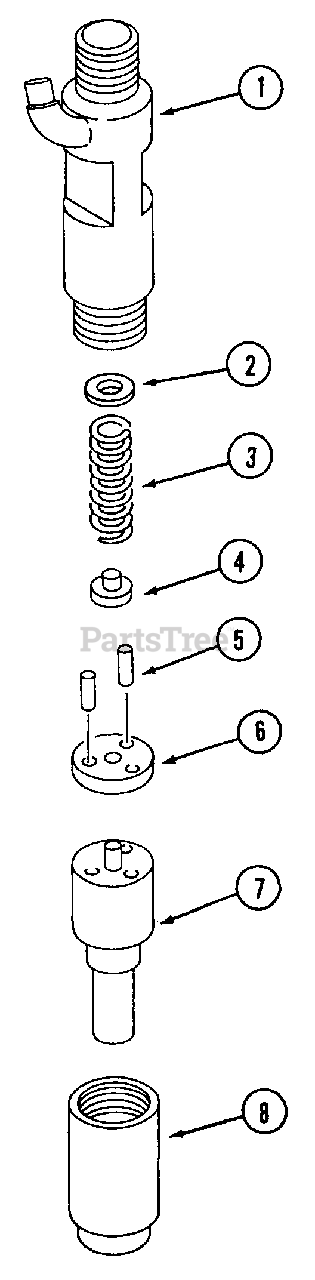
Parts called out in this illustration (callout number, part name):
1	Body Sub Ass'y.
2	Washer t=1.2
3	Spring Pressure
4	Pin, Pressure
5	Pin, Straight
6	Packing, Tip
7	Nozzle Ass'y.
8	Nut
